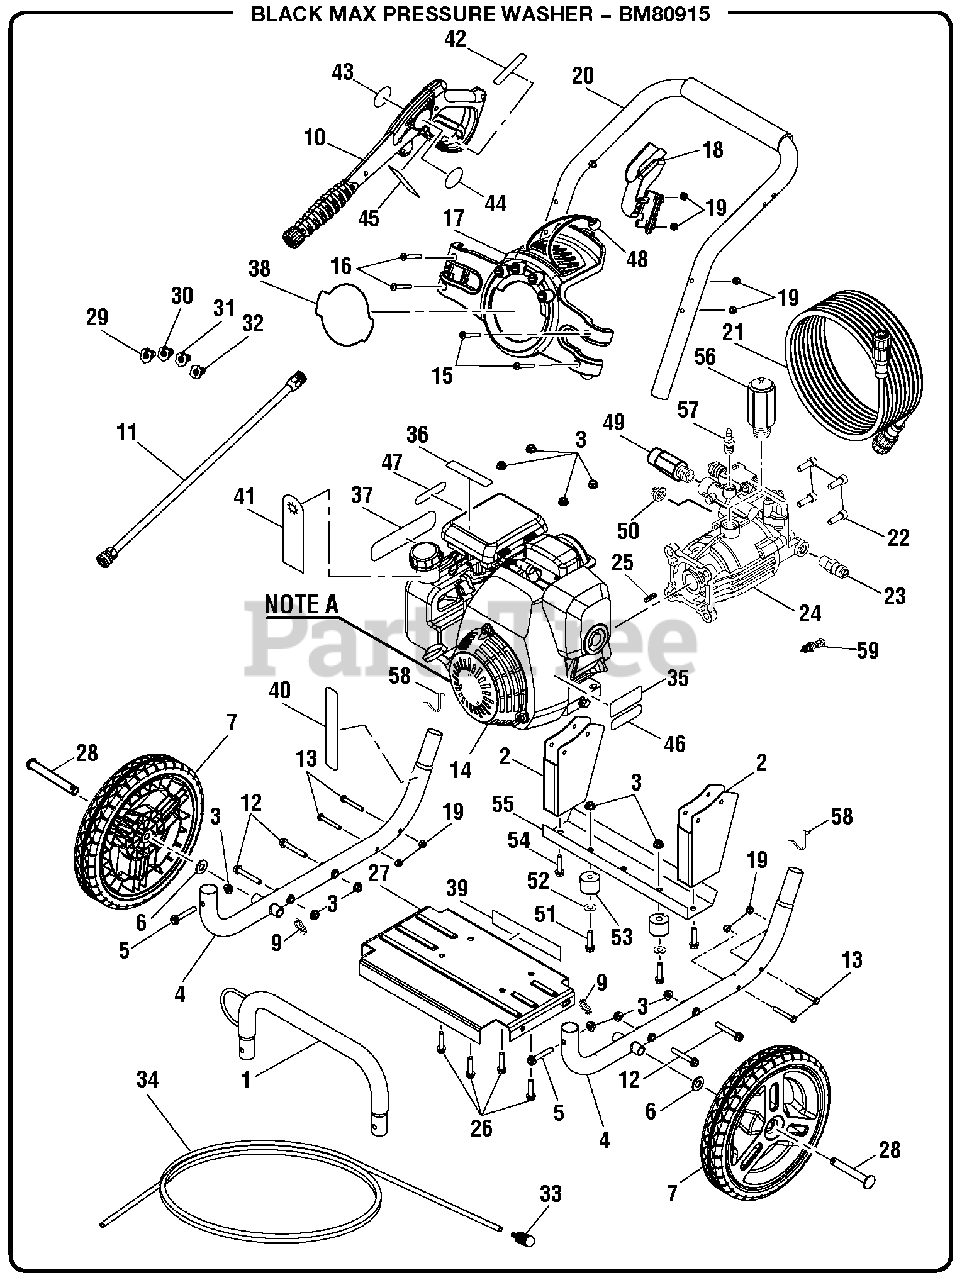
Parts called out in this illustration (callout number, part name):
1	Front Frame
2	Rear Foot
3	Hex Nut (M8 x 1-1/4 in.)
4	Main Frame Assembly
5	Bolt (M8 x 50 mm, Flange Hd.)
6	Washer (1/2 in.)
7	Wheel
8	Acorn Nut
9	Wheel Bushing (5/8 in.)
10	Trigger Handle Assembly
11	Extension Wand
12	Bolt w/Washer (M8 x 55 mm, Hex Hd.)
13	Bolt (1/4-20 x 52 mm Hex Hd.)
15	Screw (1/4-20 x 1.85 in., T30 Torx Hd.)
16	Screw (1/4-20 x 2.27 in., T30 Torx Hd.)
17	Hose and Nozzle Holder Assembly
18	Wand Holder.
19	Lock Nut (1/4-20)
20	Handle w/Foam
21	Hose (25 ft., 3000 psi)
22	Screw (5/16-24 x 23 mm Soc Hd.)
23	Thermal Release Valve
25	Output Shaft Key (3/16 in. x 40 mm)
26	Bolt (M8 x 36 mm, Flange Hd.)
27	Engine Plate
29	0deg Nozzle
30	25deg Nozzle
31	40deg Nozzle
32	Soap Nozzle
33	Detergent Injection Filter
34	Detergent Injection Tube
35	Label (Hot Surface)
36	Label (Engine Quick Start)
37	Label (Warning)
38	Label (Performance)
39	Data Label
40	Label (Pump Quick Start)
41	Label (Oil Hang Tag)
42	Label (Wand Rating)
43	Label (Wand Logo)
44	Label (Wand Warning)
45	Label (Warning)
46	Label (UL Fire Warning)
47	Label (Inquires)
48	Bungee Cord and Bead Assembly
49	Outlet Tube
50	Filter Screen (Pump Inlet)
51	Bolt (1/4-20 x 25 mm, Hex Hd.)
52	Washer (1/4 in.)
53	Rubber Foot
54	Bolt (1/4-20 x 19 mm)
57	Detergent Suction Kit
58	Lock Button w/Spring Clip.
59	Unloader Valve
